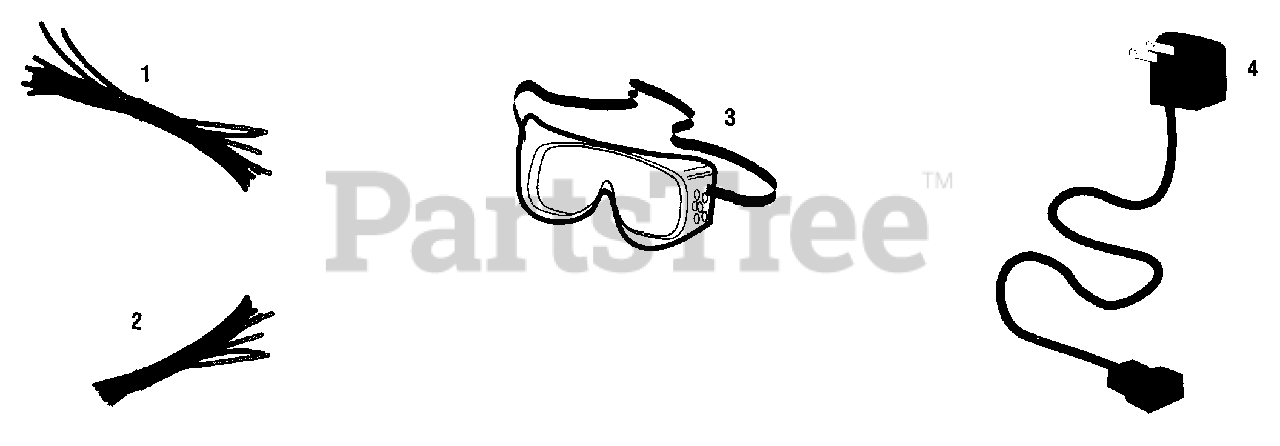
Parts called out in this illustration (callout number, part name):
1	Trimmer String Kit, .155"
2	Trimmer String Kit, .130"
3	Safety Goggles
4	Battery Charger
